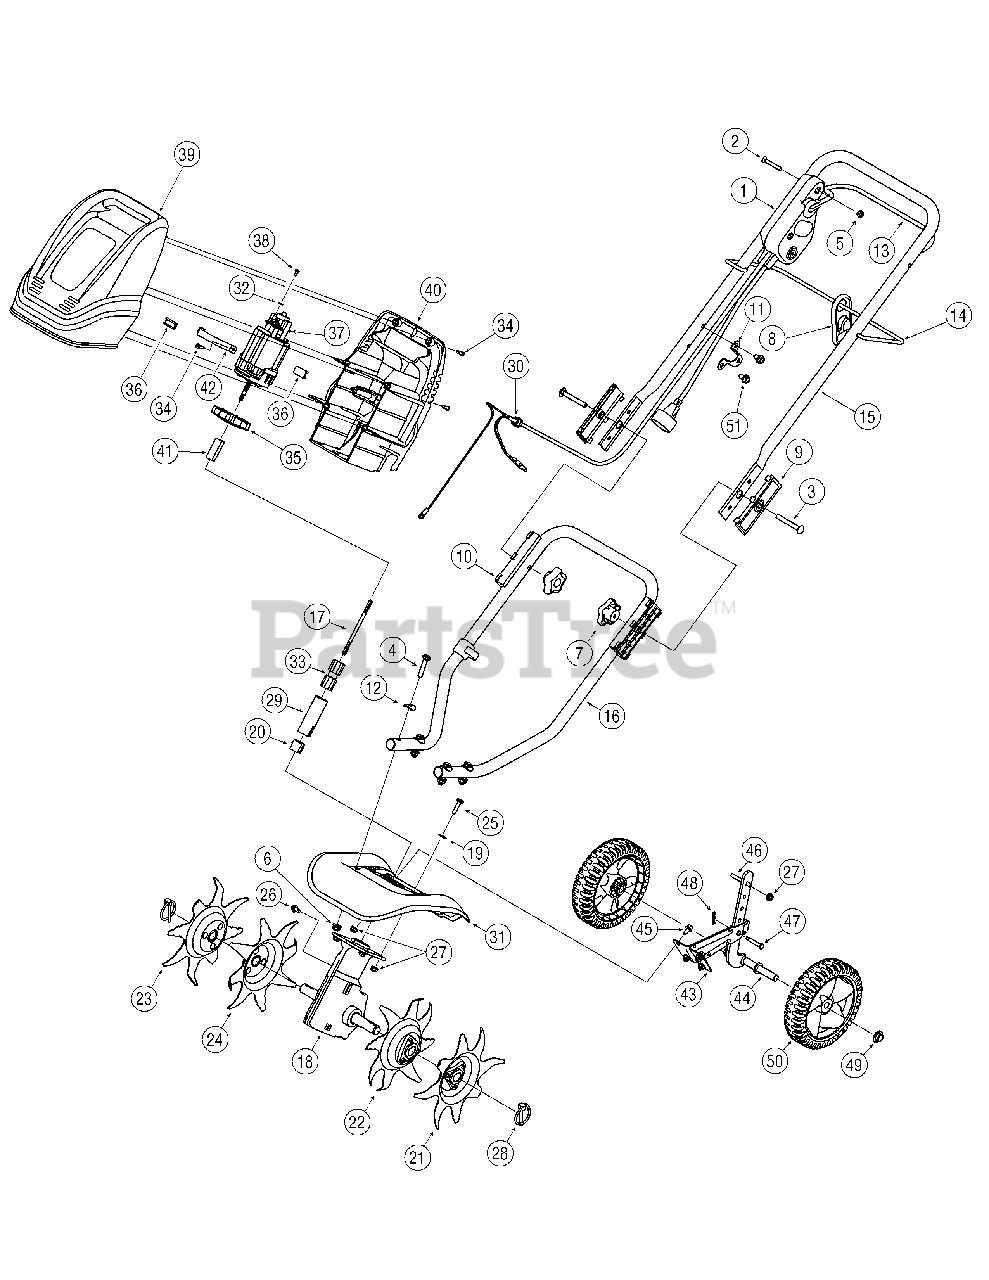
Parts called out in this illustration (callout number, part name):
1	Switch Assembly
2	Screw, T27, 1/4-20, 1.75"
3	Bolt, Carriage, 5/16-18, 2.50, Gr1
4	Hex Screw, 5/16-18, 1.50, Gr5
5	Nut, Hex Lock, 1/4-20, Gr8, Nylon
6	Nut, Flange Lock, 5/16-18, GrF, Nylon
7	Knob, Nut, 5/16-18
8	Cord Retainer
9	Insulator, Upper Handle
10	Insulator, Lower Handle
11	Cord Mount Bracket (use with 749-04244 & 710-0604A) Shown
11	Guide Cable Cord (use with 749-1295A)
12	Washer, Saddle, 320 x .93 x .060
15	Handle, Upper (use with 786-04295 & 710-0604A) Shown
15	Handle, Upper (use with 731-1820)
17	Flex Shaft, 4.5"
18	Gearbox
19	Washer, Flat
20	Sleeve
21	Tine Assembly, Outer
22	Tine Assembly, Inner
23	Tine Assembly, Outer
24	Tine Assembly, Inner
25	Hex Screw, 1/4-20, 1.00, Gr5
26	Bolt, Hex Washer 1/4-20, .50
27	Nut, Flange Lock, 1/4-20, GrF, Nylon
28	Lynch Pin, .1875
30	Bushing, Cord
31	Tine Shield
32	Washer, Lock, #10
33	Tube w/ Spacers
34	Screw, .750
35	Fan
36	Motor Pad, 1"
37	Motor Assembly, 120 V
38	Screw, #8-32 x .312
39	Motor Cover, Front
40	Motor Cover, Rear
41	Motor Hub
42	Motor Strap
43	Bracket Assembly, Tail Piece
44	Support Bracket Assembly, Wheel
45	Hex Flange Screw, 1/4-20, .50, Gr5
46	Belt Guard Pin 1/4 Dia. x 1.43
47	Clevis Pin, .250 x 1.53
48	Cotter Pin, .072 Dia. x 1.13
49	Push Cap, 1/2"
50	Wheel, 7 x 1.8 Spoke Bar Gray
51	Screw, 5/16-18, 0.625" Shown
